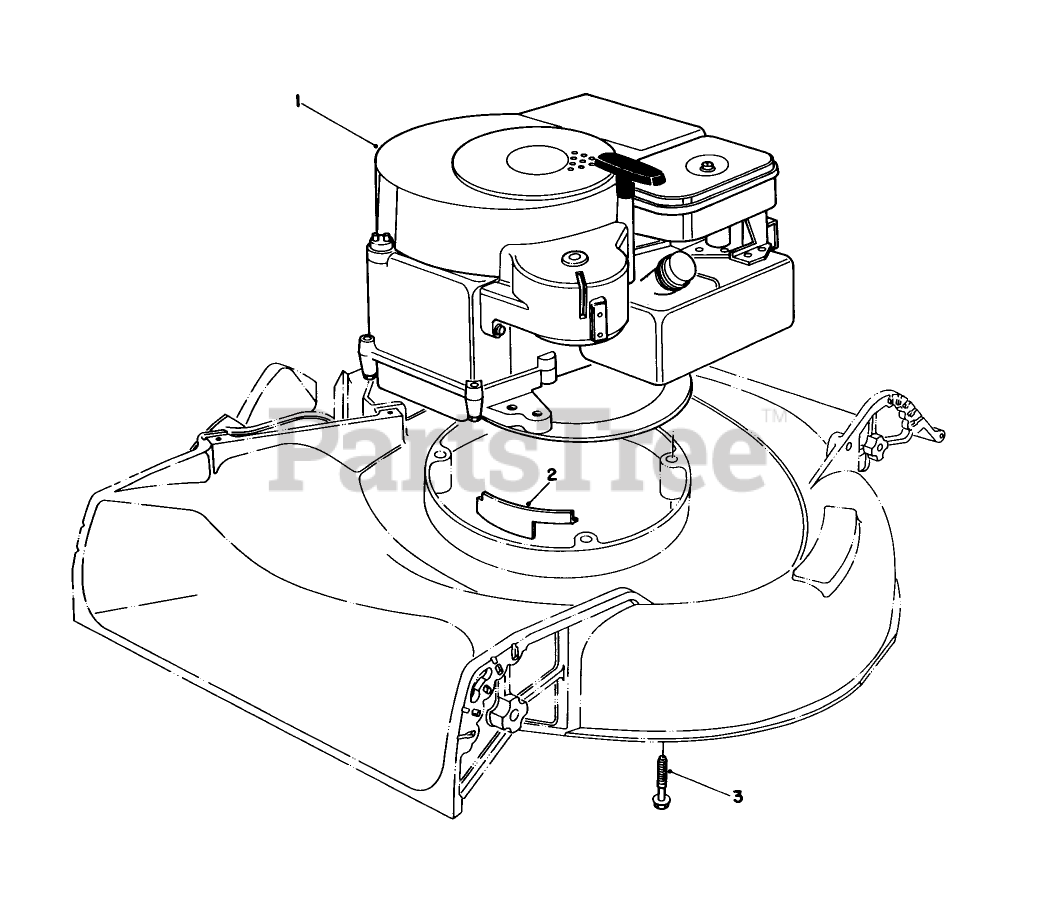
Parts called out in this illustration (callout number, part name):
1	Engine
2	HOUSING CAP
3	3/8-16 X 2-3/4 CAPSCR
